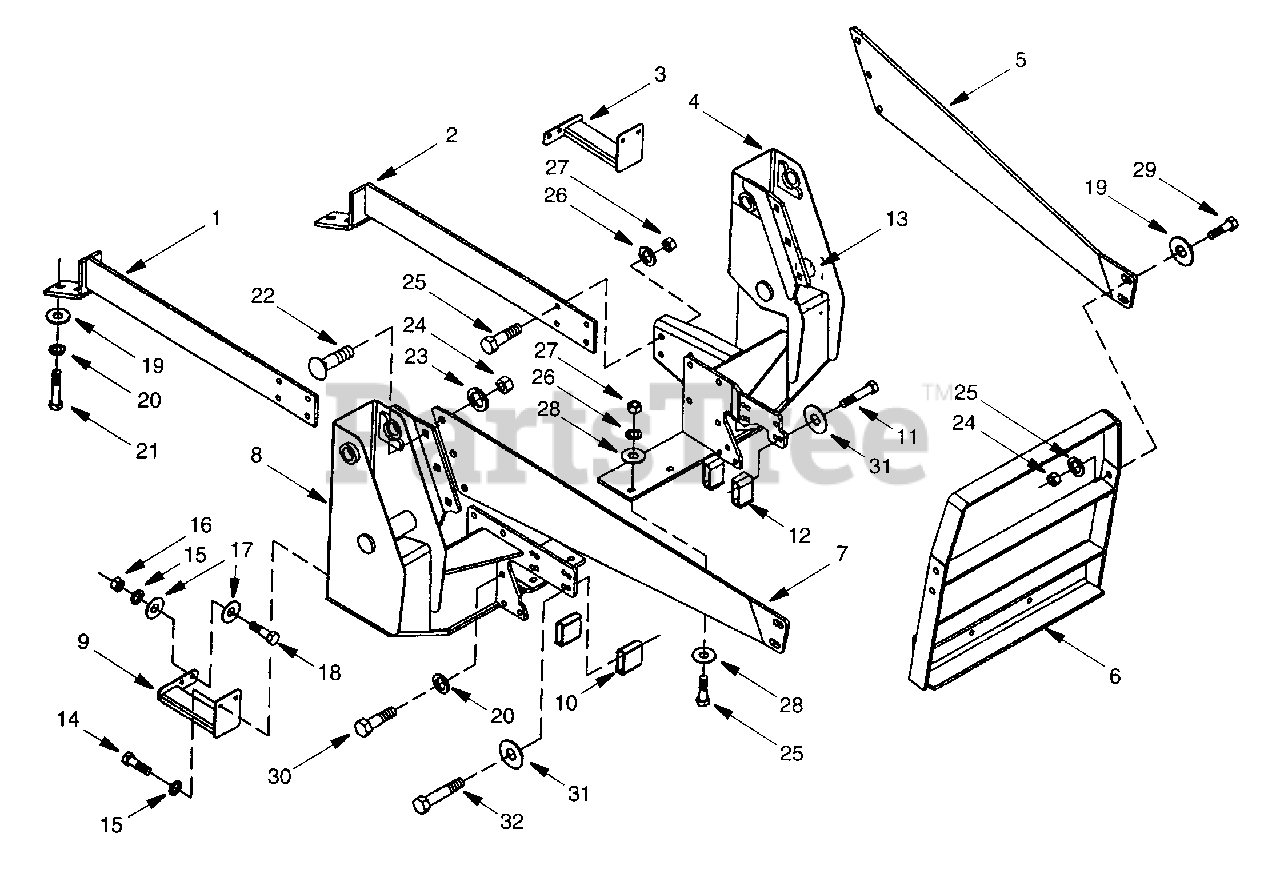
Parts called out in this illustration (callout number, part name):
1	Rear Support, RH
2	Rear Support, LH
4	Loader Mount, LH
5	Side Frame, LH
6	Front Mount
7	Side Frame, RH
8	Loader Mount, RH
10	Spacr, 1.715 (Tractor Model 7300/05)
11	Hex Hd Cap Scrw, 12mm x 1.25 x 90 (Tractor Model 7260/65)
12	Spacr, 1.715 (Tractor Model 7260/65)
13	Loader Mounting Label
14	Self Tapping Screw, .38 x 1.25
15	Lockwasher, 3/8
16	Plated Hex Nut, 3/8
17	Washer, 3/8
18	Hex Hd Cap Scrw, 3/8 NC x 1 GR 5
19	Flat Washer, 5/8
20	Lockwasher, 9/16
21	Hex Hd Cap Scrw, M14-2 0 x 50 mm
22	Carriage Bolt, 5/8 x 1.5 GR5
23	Lockwasher, 5/8
24	Plated Hex Nut, 5/8
25	Hex Hd Cap Scrw, 1/2 x 1.5 GR5
26	Lockwasher, 1/2
27	Plated Hex Nut, 1/2
28	Flat Washer, 1/2
29	Hex Hd Cap Scrw, 5/8 x 1.75 GR5
30	Hex Hd Cap Scrw, M14-2.0 x 30mm
31	Washer, 488 x 1.25 x .134
32	Hex Hd Cap Scrw, 12mm x 1.25 x 100 (Tractor Model 7260/65)
